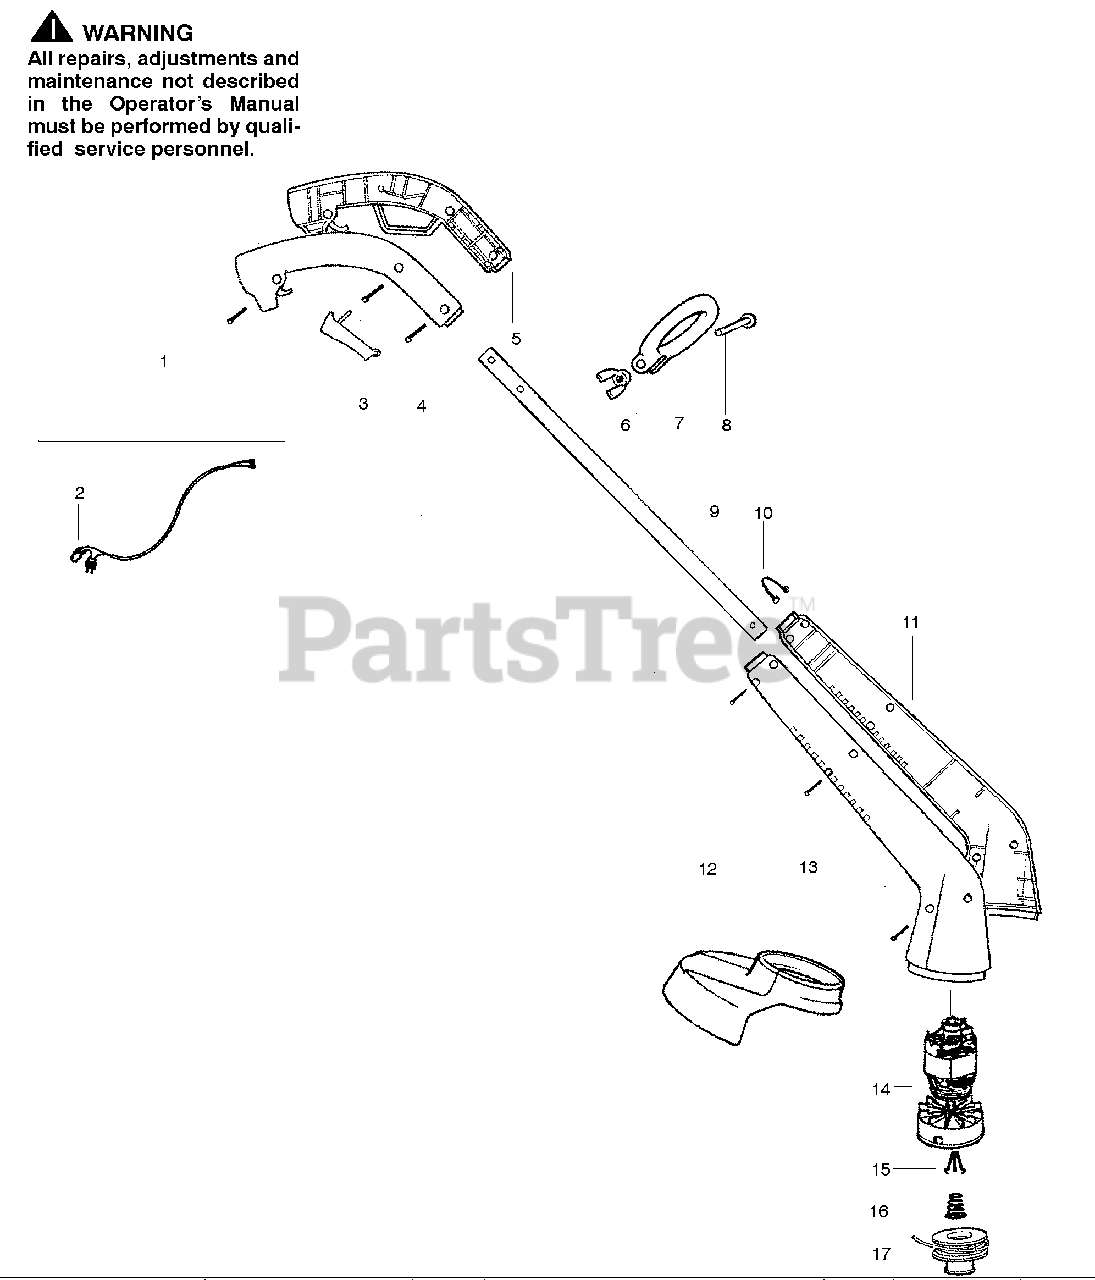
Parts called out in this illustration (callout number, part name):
1	Assy-Wire Harness
5	Handle Set
6	Wing Nut
7	Assist Handle
9	Tube w/Decal
10	Snap Button
11	Housing Set
12	Shield w/Limiter
14	Motor/Hub Ass'y
15	Retainer-Spool
16	Spring-Return
17	Accy-Spool w/ Line
